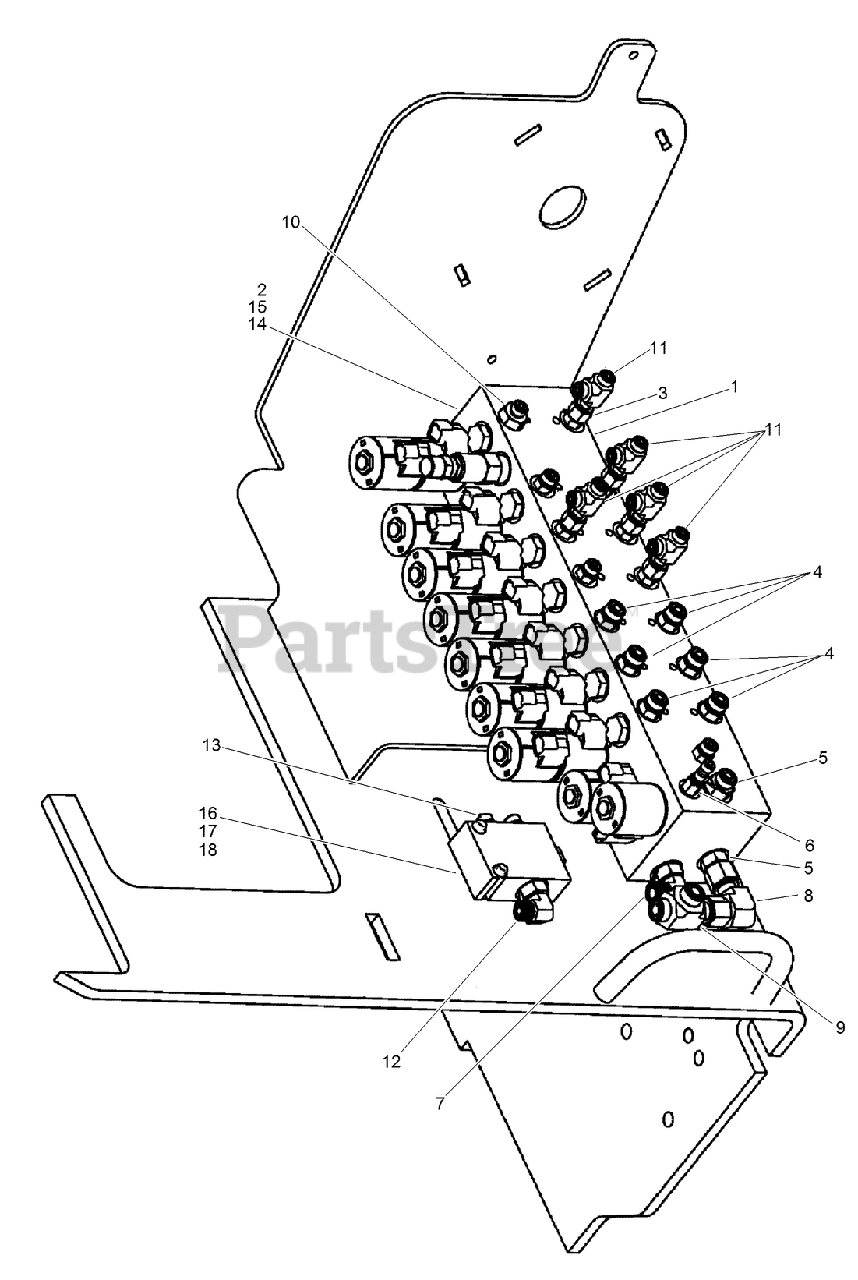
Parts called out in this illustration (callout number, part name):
1	KIT - Hydraulic Fittings
2	9 SECTION HYD VALVE ASM
3	CONNECTION - Straight, -4 ORFS / -6 ORB
4	CONNECTION - Straight, -6 ORFS / -6 ORB
5	CONNECTION - Straight, -6 ORFS / -8 ORB
6	COUPLING - Quick Disconnect
7	CONNECTION - 90 Deg, -8 ORFS / -8 ORB
8	CONNECTION - 90 Deg, -8 ORFS / -8 ORFS
9	CONNECTION - Run Tee, -8 ORFS / -8 ORFS
10	FITTING-STR,ORIF
11	CONNECTION - Run Tee, -4 ORFS / -4 ORFS
12	CONNECTION - 90 Deg, -4 ORFS / -8 ORB
13	CONNECTION - Straight, -4 ORFS / -4 ORB
14	WASHER-FLAT
15	SCREW-HH
16	HYD FLOW DIVIDER VALVE ASM
17	SCREW-FLANGE, METRIC
18	NUT, METRIC FLANGE PREVAILING - M6 Zinc
